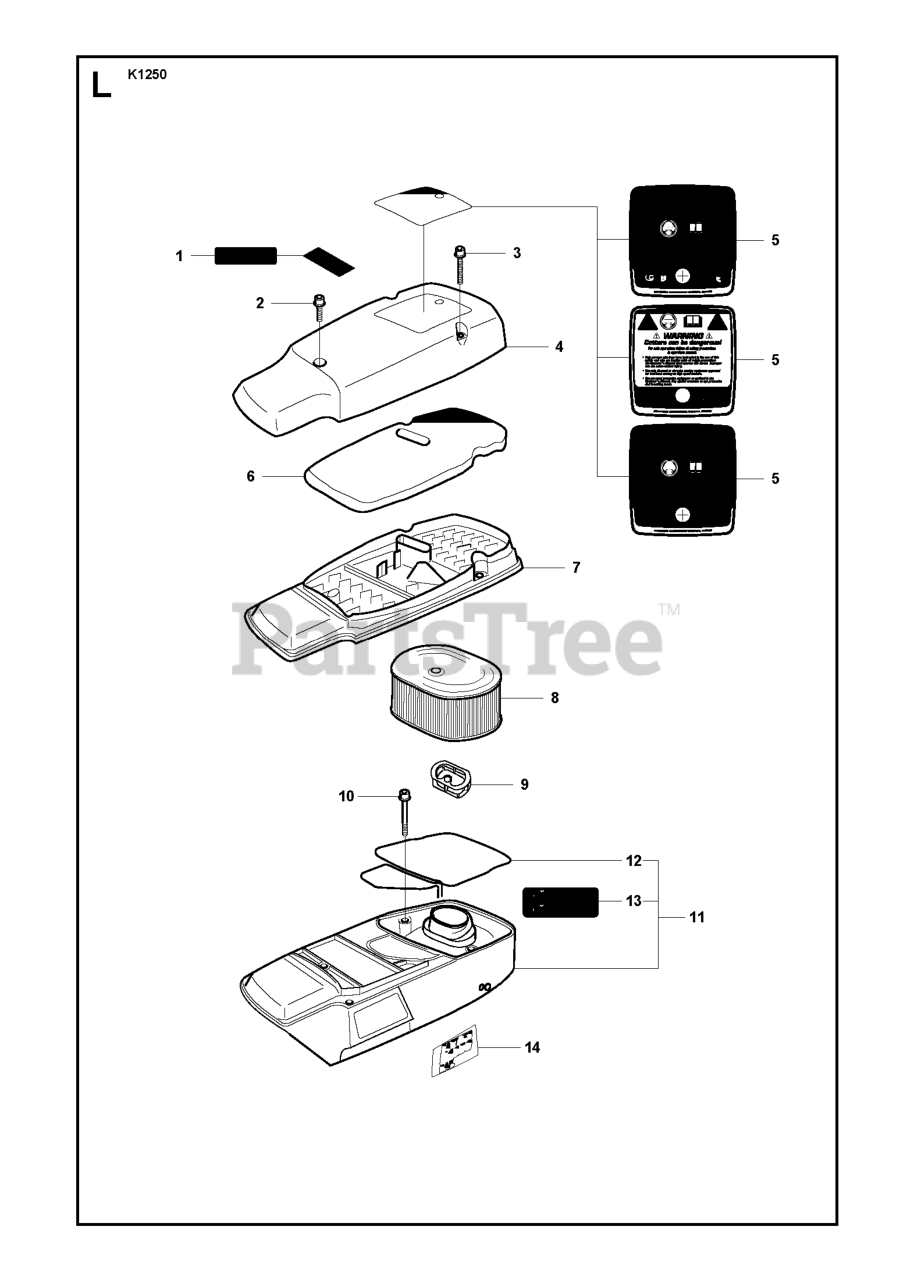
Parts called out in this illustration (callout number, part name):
2	SCREW
4	FILTER COVER
5	RP LABEL - INSTRUCTIONS
5	LABEL
6	AIR FILTER
7	FILTER BOTTOM
8	RP AIR FILTER PAPER
9	CONNECTION
11	CYLINDER COVER
14	LABEL
